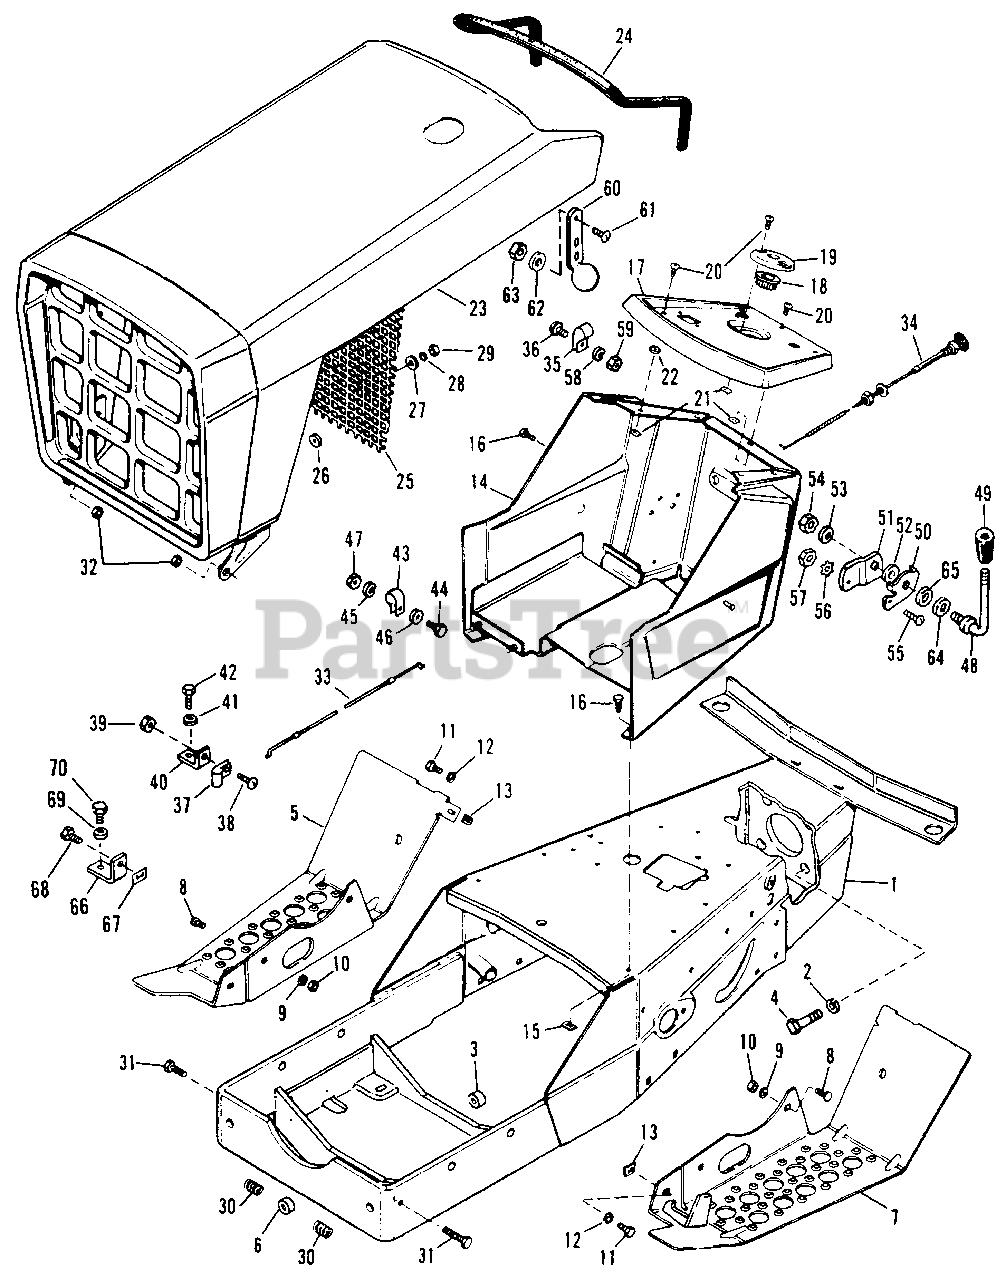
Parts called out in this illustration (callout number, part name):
1	Frame Assembly
2	Lockwasher, 7/16"
4	Hex Capscrew, 7/16"-14 N.C. x 1-1/2"
5	Foot Rest, R.H.
7	Foot Rest, L.H.
8	Carriage Bolt, 5/16"-18 N.C. x 3/4"
9	Lockwasher, 5/16"
10	Full Hex Nut, 5/16"-18 N.C.
11	Hex Capscrew, 5/16"-18 N.C. x 3/4"
12	Lockwasher, 5/16"
13	Nut, Tinnerman, 5/16"-18 N.C.
14	Dash Assembly
15	Nut, Tinnerman
16	Hex Head Self Tapping Screw, No. 14 AB x 3/4"
17	Panel, Instrument
18	Bushing, Steering
19	Plate, Steering Adj.
20	Round Head Phillips Screw, 1/4"-20 N.C. x 1/2"
21	Nut, Tinnerman, 1/4"-20 N.C.
22	Plain Washer
23	Grille & Hood Assembly
24	Molding, Hood
25	Screen, Grille
28	Lockwasher, Shakeproof No. 10
29	Full Hex Nut, No. 10-24 N.F.
31	Hex Capscrew, 3/8"-16 N.C. x 1-1/2"
32	Hex Lock Nut, Center, 3/8"-16 N.C.
33	Throttle Control
34	Choke Control
35	Clip, Bowden Wire
36	Self Tapping Rd. Hd. Screw, No. 10-24 N.C. x 1/2"
37	Clip, Bowden Wire
38	Rd. Hd. Machine Screw, No. 10-32 N.F. x 3/8"
39	Full Hex Nut, No. 10-32 N.F.
40	Bracket, Throttle Cable
41	Lockwasher, 1/4"
42	Self Tapping Rec. Hex Hd. Screw, 1/4"-20 N.C. x 5/8"
44	Hex Capscrew, 1/4"-20 N.C. x 5/8"
45	Lockwasher, 1/4"
46	Plain Washer, 1/4" Std.
47	Full Hex Nut, 1/4"-20 N.C.
48	Throttle Handle
49	Knob
50	Stop Throttle
51	Arm Throttle
53	Washer Lock Dished Type, 3/8"
54	Full Hex Lock Nut, 3/8"-16 N.C.
55	Round Hd. Machine Screw, No. 10-32 x 1/2"
56	Lockwasher, Shakeproof, No. 10
57	Full Hex Nut, No. 10-32
58	Lockwasher, No. 12
59	Full Hex Nut, No. 10-24
61	Phillips Head Truss Screw, No. 10-32 x 1/2"
63	Lock Nut, No. 10-32
66	Bracket, Pulley Guard
67	Nut, Tinnerman
68	Hex Capscrew, 1/4"-20 x 3/4"
69	Plain Washer, 3/16
70	Hex Capscrew, No. 14 x 1-1/4"
